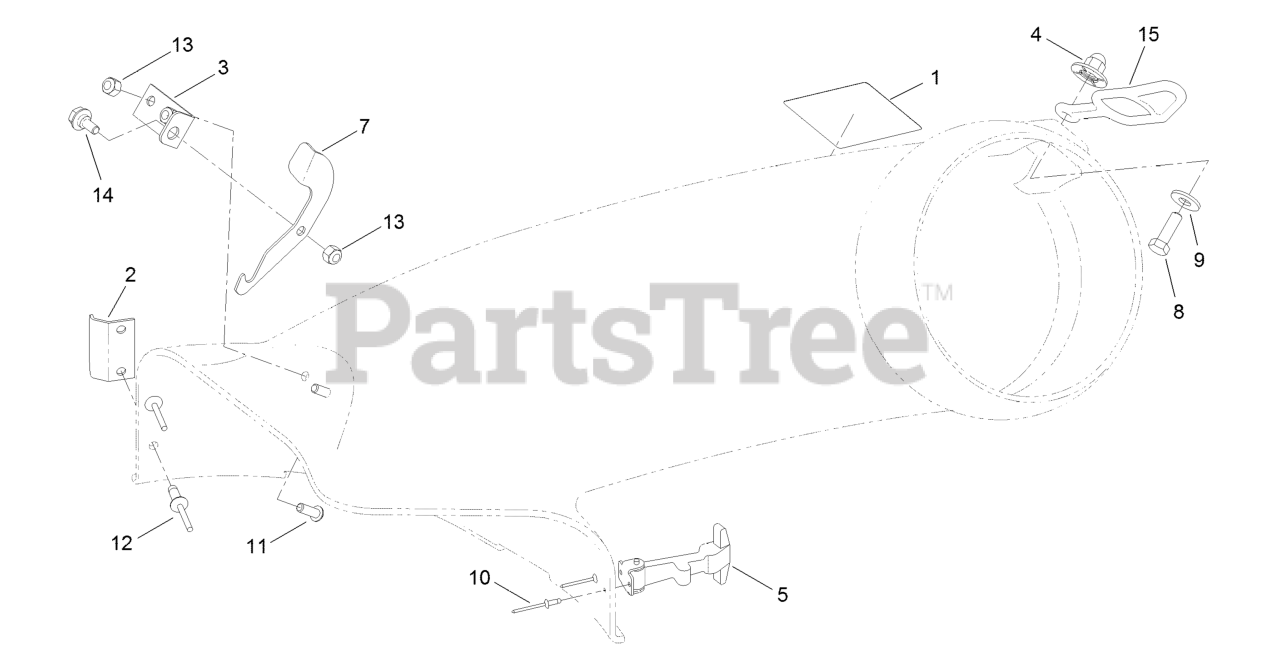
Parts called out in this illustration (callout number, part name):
1	DECAL-DANGER
2	BRACKET-ELBOW
3	PLATE-PIVOT
4	NUT-IMPELLER
5	HANDLE ASM
8	SCREW-HH
9	WASHER-FLAT
10	RIVET-POP
11	SCREW-HSBH
12	RIVET-BLIND
13	NUT-LOCK, NI
15	RETAINER-DUCT
